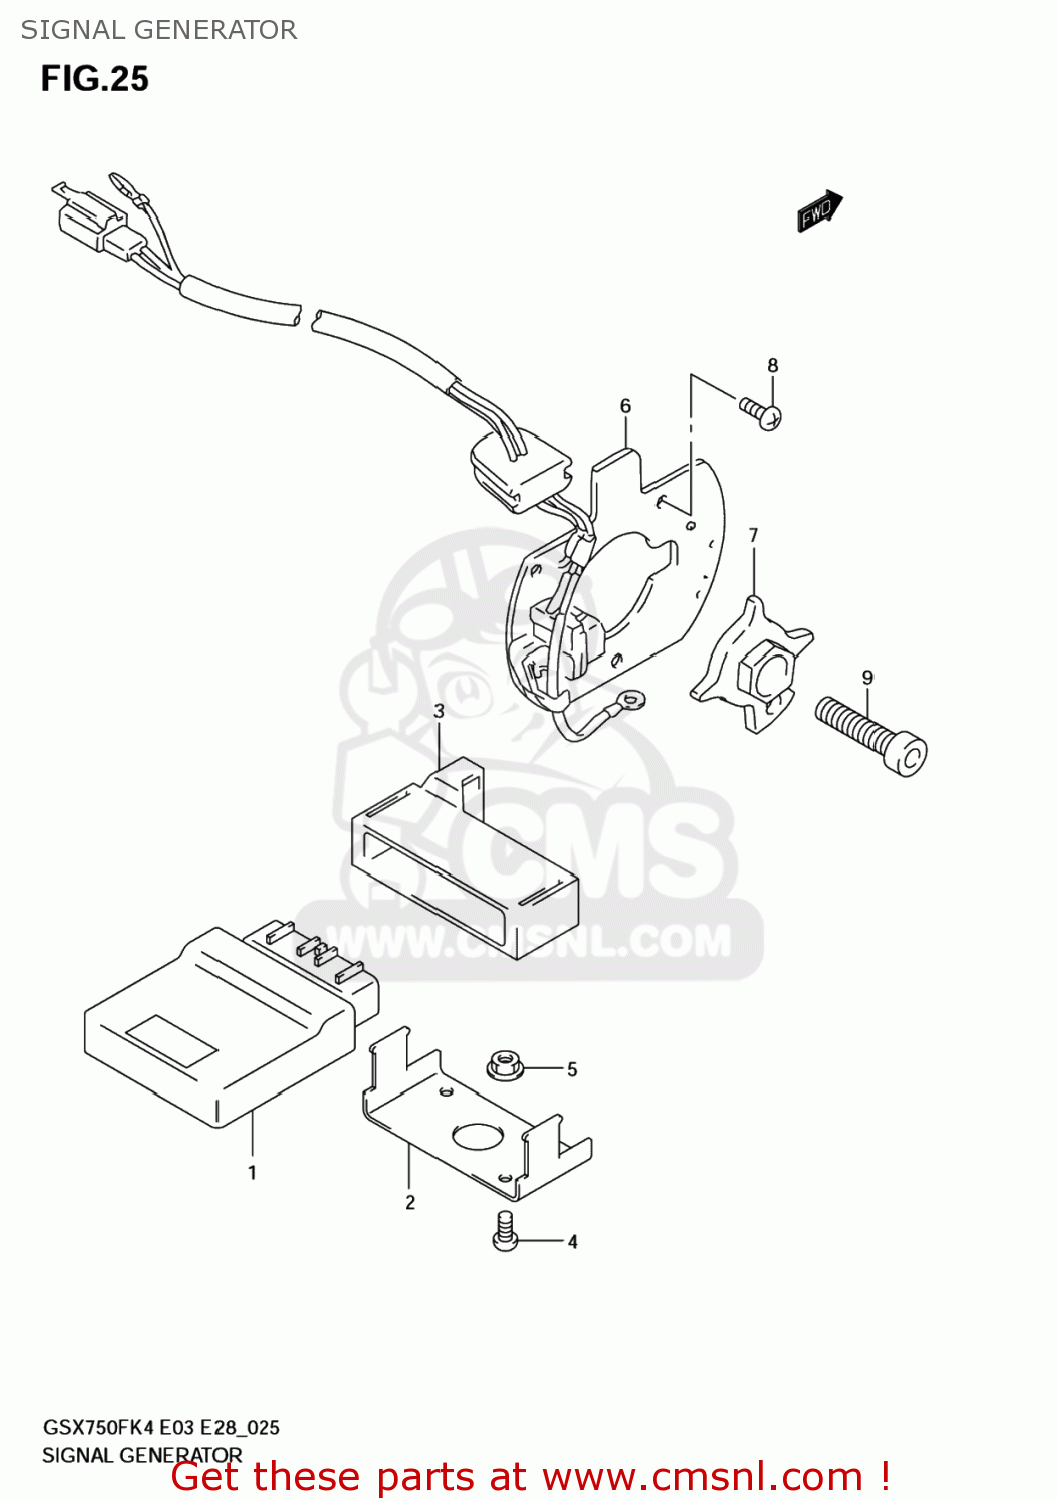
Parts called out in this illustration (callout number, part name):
1	IGNITOR ASSY
2	BRACKET,IGNITOR
3	COVER,IGNITOR
4	SCREW 5X12
5	NUT
6	STATOR,SIGNAL GENERATOR
7	ROTOR,SIGNAL GENERATOR
8	SCREW
9	BOLT
